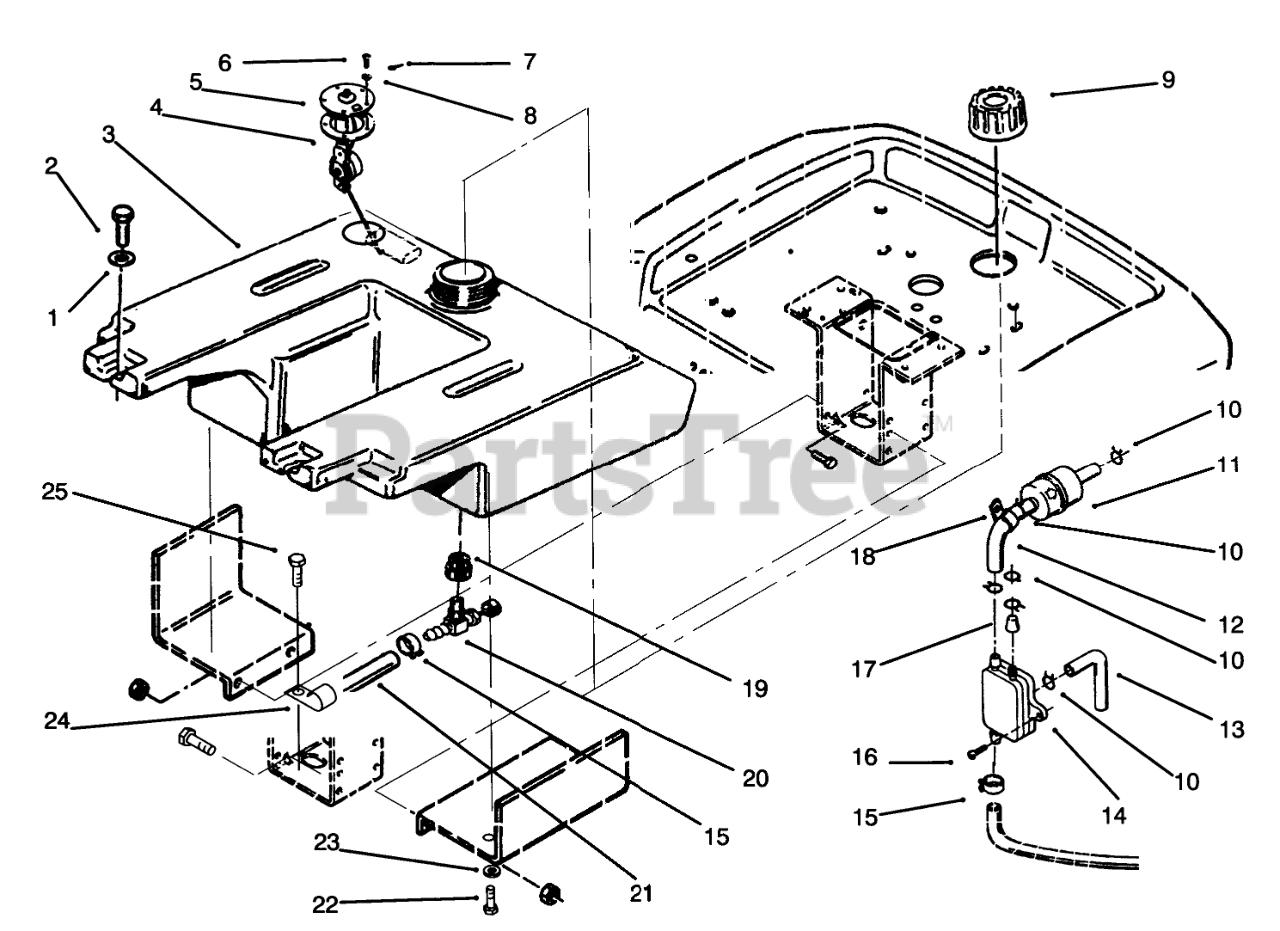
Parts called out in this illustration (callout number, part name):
1	WASHER-FLAT
3	Tank-Fuel (Incl. Ref. #19 & 20)
4	GASKET-SENDER, FUEL
5	SENDER-FUEL LEVEL
6	Screw
7	TERMINAL-GROUND
8	WASHER-LOCK
9	GAS CAP ASM
10	CLAMP-HOSE
11	Filter-Fuel
12	Hose
13	Hose
14	Fuel Pump
15	Clamp
16	SCREW-TAPPING PAN HD
17	Cap
18	CLAMP
19	BUSHING
20	VALVE-FUEL
21	FUEL HOSE 75" OF 6554
22	SCREW-HH
23	WASHER-LOCK
24	Clip
25	SCREW-HH, LOCK
